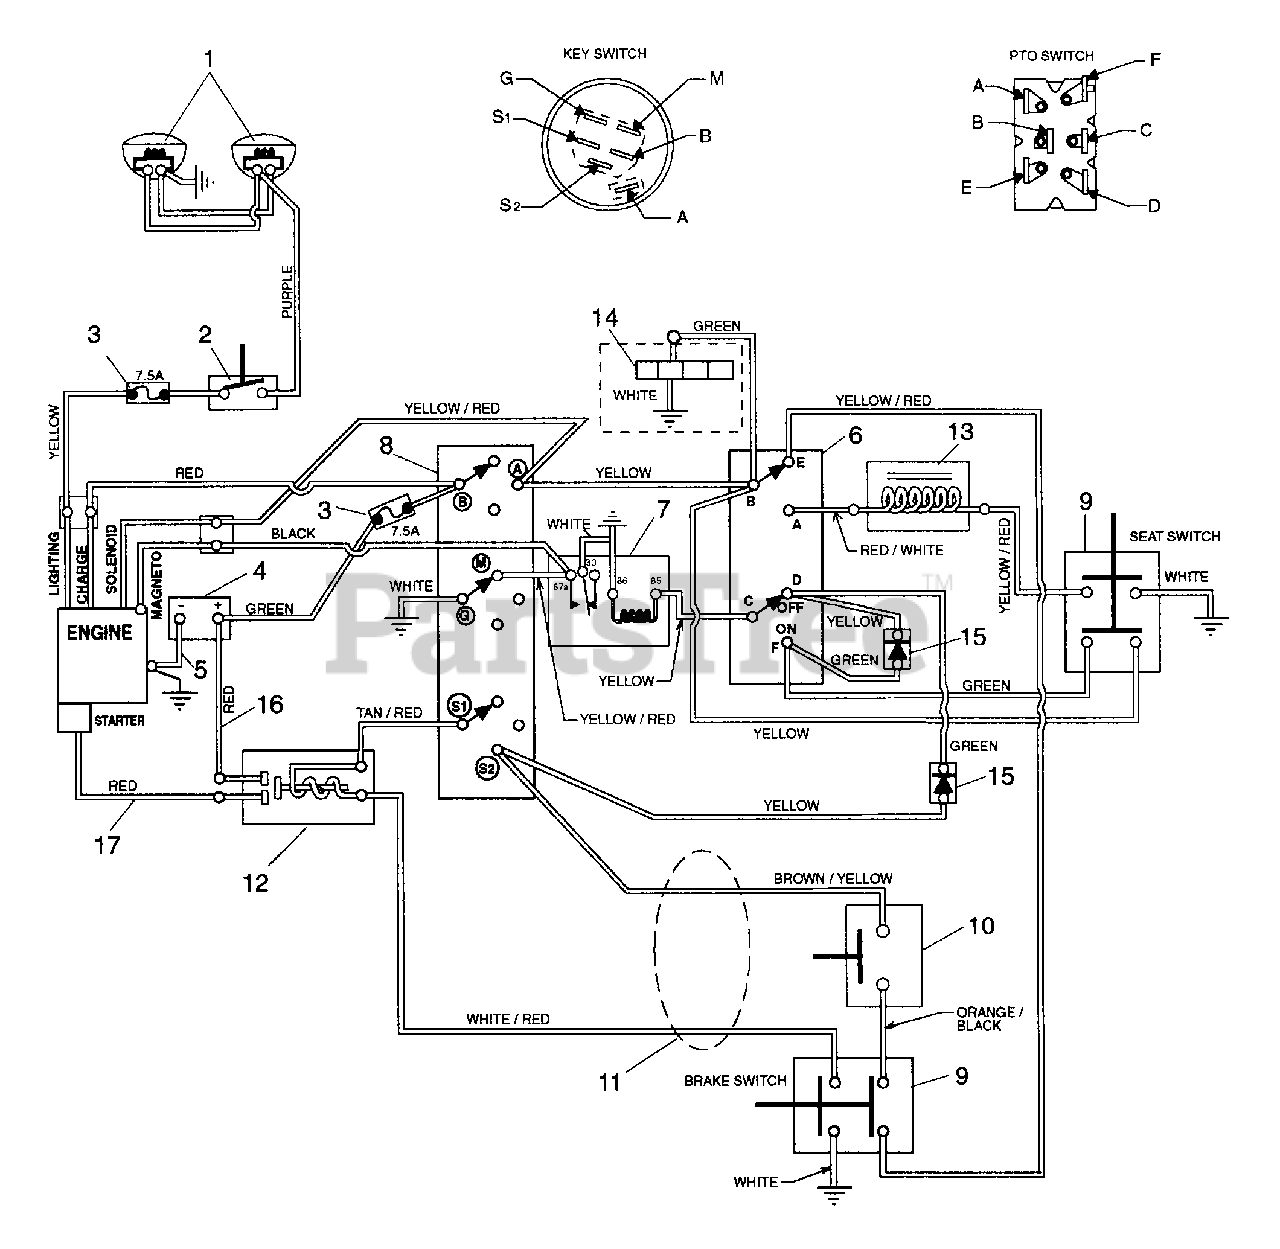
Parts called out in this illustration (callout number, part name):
1	HEADLIGHT- L.H.
1	HEADLIGHT- R.H.
2	LIGHT SWITCH
3	7.5 Amp Fuse
4	BATTERY W/ TUBE
5	GROUND CABLE .31X22.00X.31
6	SWITCH ASSEMBLY- PTO
7	RELAY
8	KEY SWITCH
9	SWITCH- DOUBLE POLE N.O./N.O.
10	SWITCH-NEUTRAL START N.O.
11	WIRE HARNESS- LT14
12	SOLENOID
13	ELECTRIC CLUTCH/BRAKE(1.8AMP)
14	HOURMETER
15	MOLDED DIODE PLUG 1 AMP
16	START CABLE 22"
17	STARTER CABLE 6.75"
